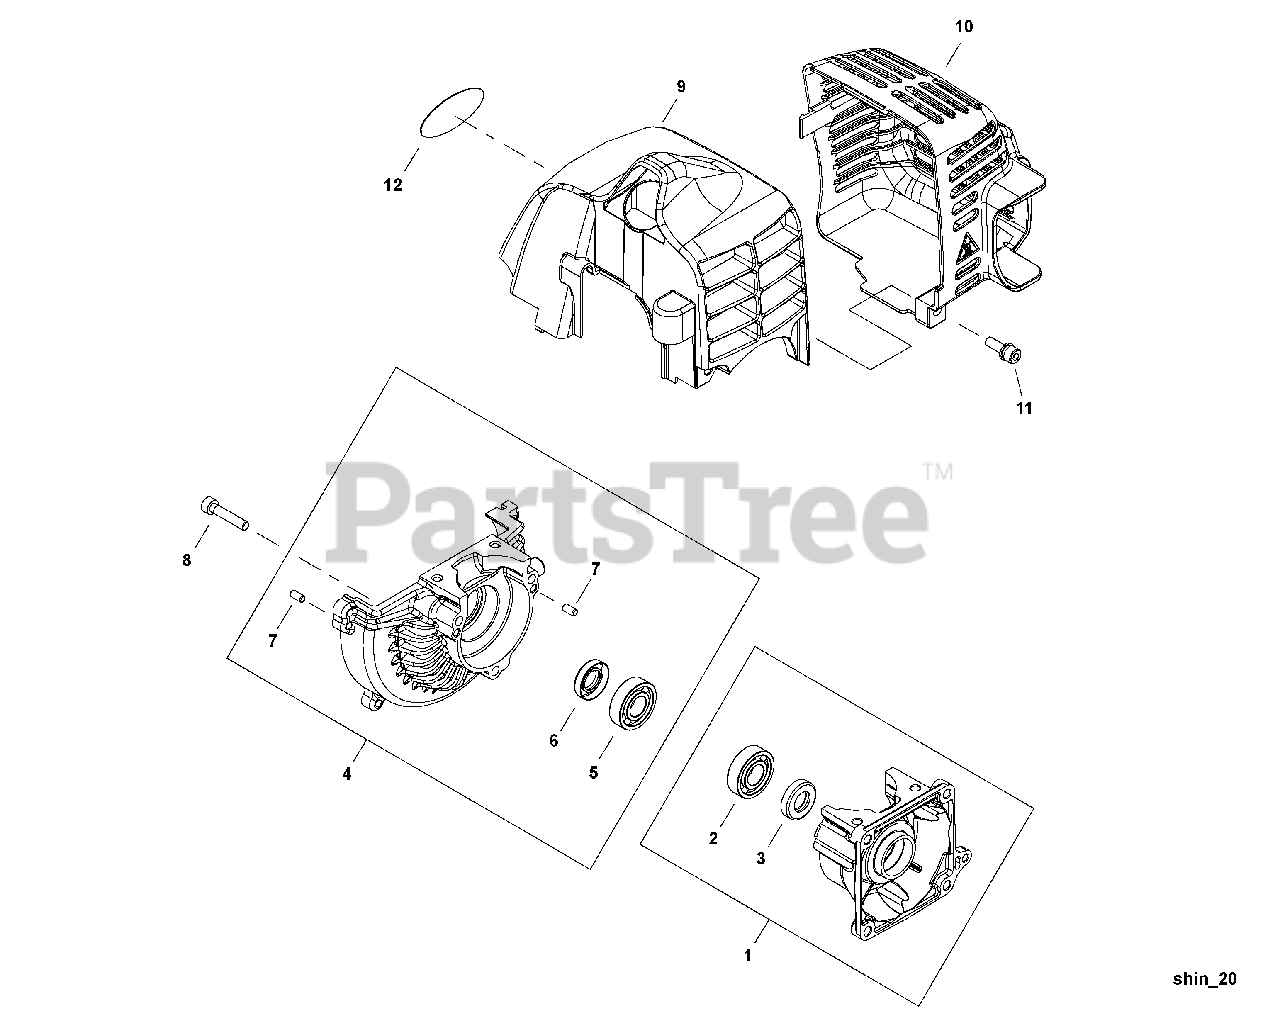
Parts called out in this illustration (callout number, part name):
1	CRANKCASE ASSY - REAR
2	BEARING, BALL - 6201C3
3	SEAL, OIL
4	CRANKCASE ASSY - FRONT
5	BEARING, BALL - 6201C3
6	SEAL, OIL
7	PIN - LOCATING
8	SCREW - 5X25
9	COVER, ENGINE
10	COVER, MUFFLER
11	SCREW - 5X20
12	LABEL - MODEL 282
